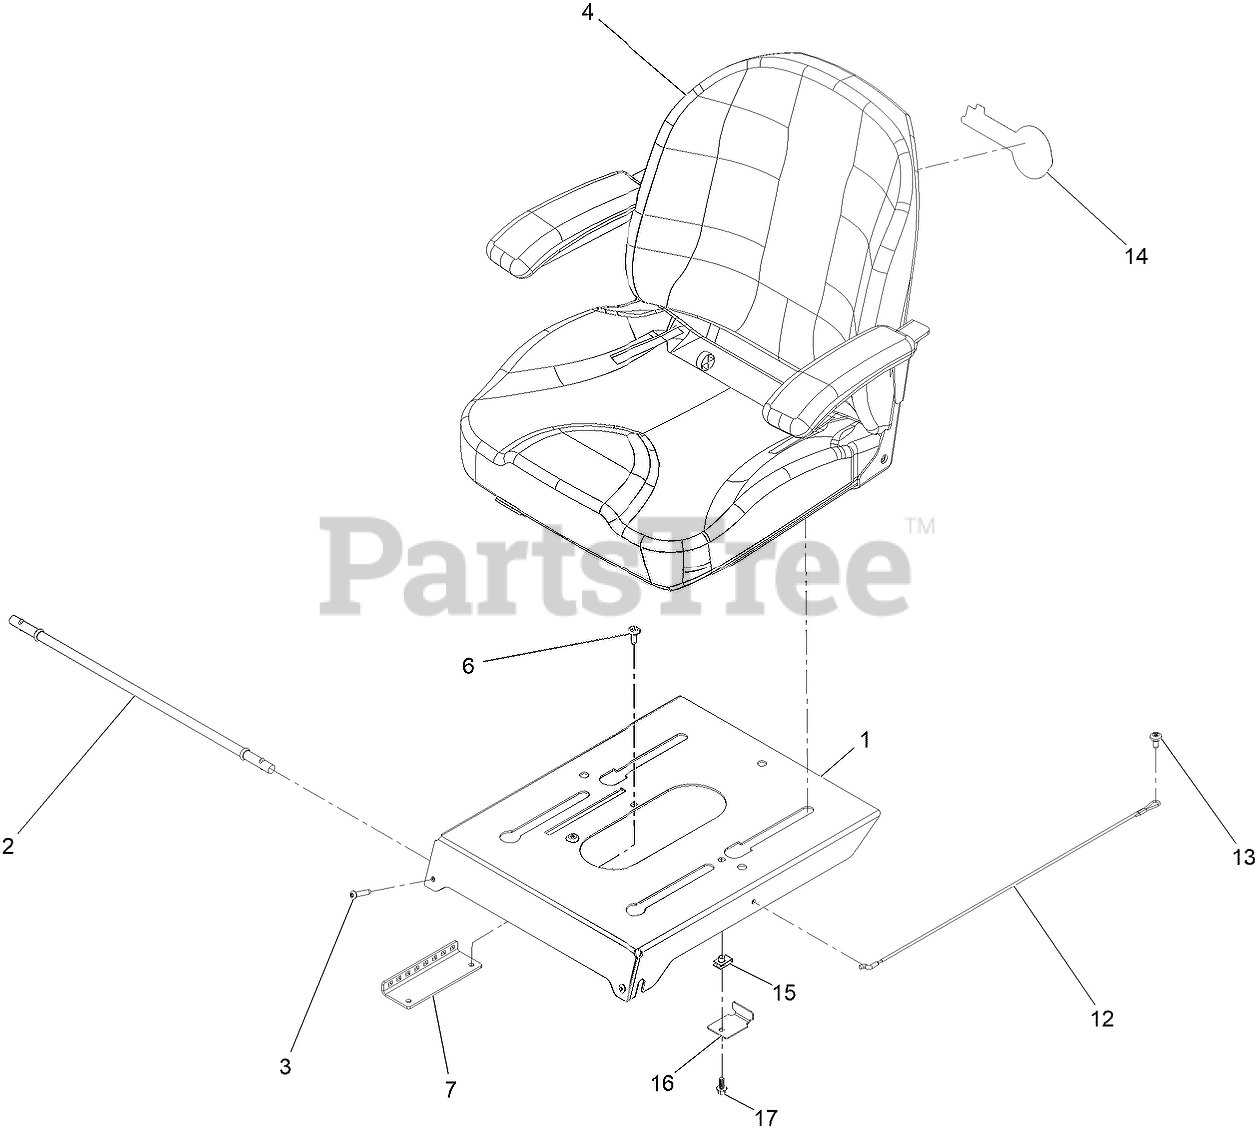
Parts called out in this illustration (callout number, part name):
2	ROD-PIVOT
3	SCREW-TTH, THREAD ROLLING
4	SEAT ASM, EXMARK
7	BRACKET-LATCH, SEAT
12	CABLE-LANYARD
13	SCREW-SHOULDER
14	DECAL-EXMARK LOGO
16	Bracket-Stop, Seat
17	SCREW-HHF
